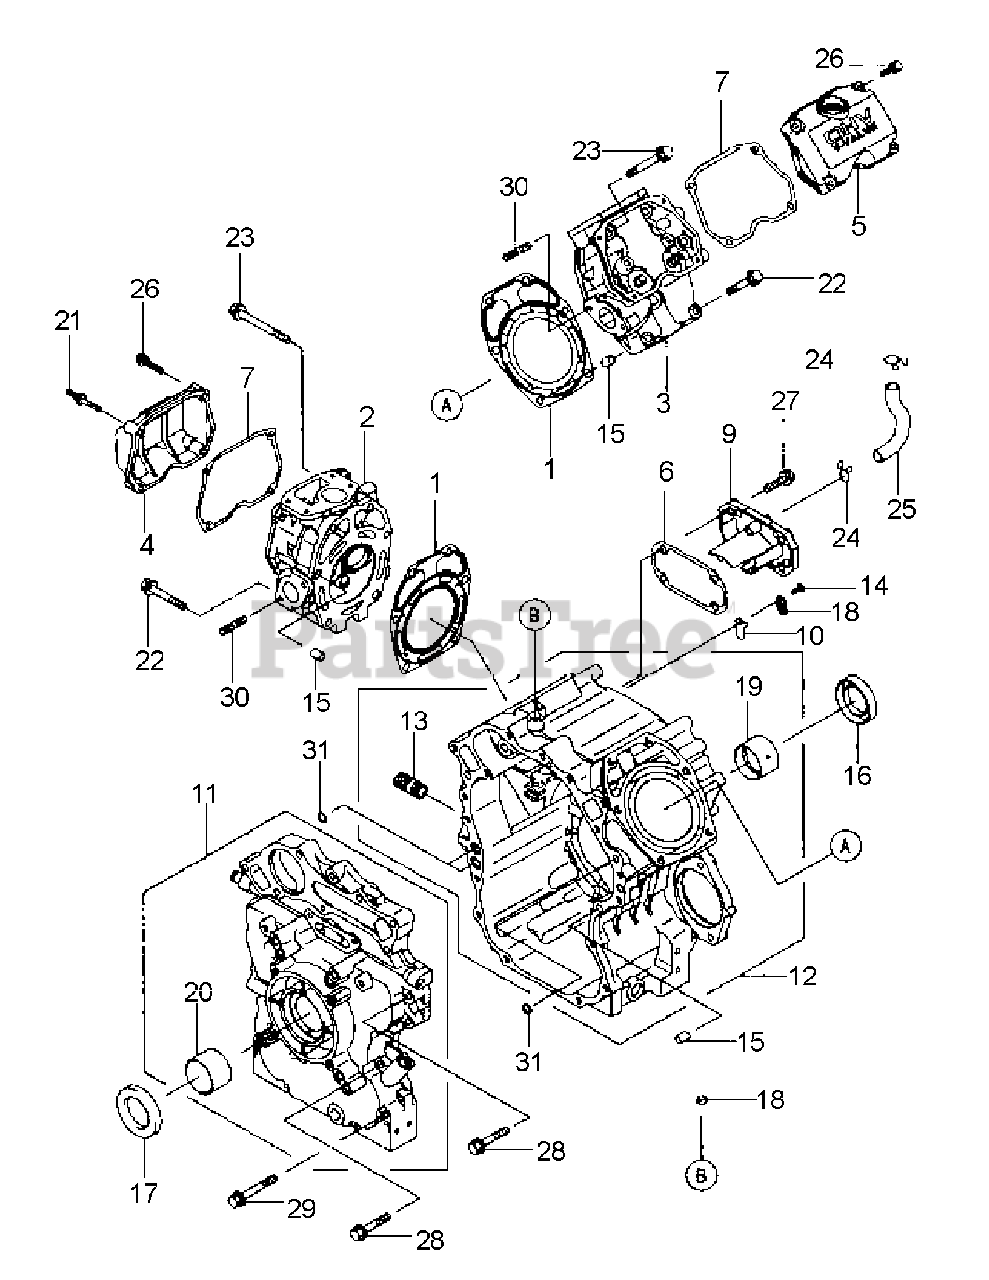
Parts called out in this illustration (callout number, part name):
2	HEAD-COMP-CYLINDER, #2
3	HEAD-COMP-CYLINDER, #1
6	GASKET, BREATHER
7	GASKET, ROCKER CASE
9	BREATHER COVER
10	BREATHER VALVE
11	COVER-CRANKCASE
12	CRANKCASE-COMP
16	SEAL-OIL,SD 38X58X11 AE
17	SEAL-OIL, SD 42X65X9 AE
18	SEAL, DS 8x12x3
19	PLANE BEARING
20	PLANE BEARING
22	BOLT 8x60
23	BOLT 8x85
26	BOLT-FLANGED
27	BOLT-FLANGED
28	BOLT-FLANGED
29	BOLT-FLANGED
30	BOLT-STUD
31	O-RING 11mm
